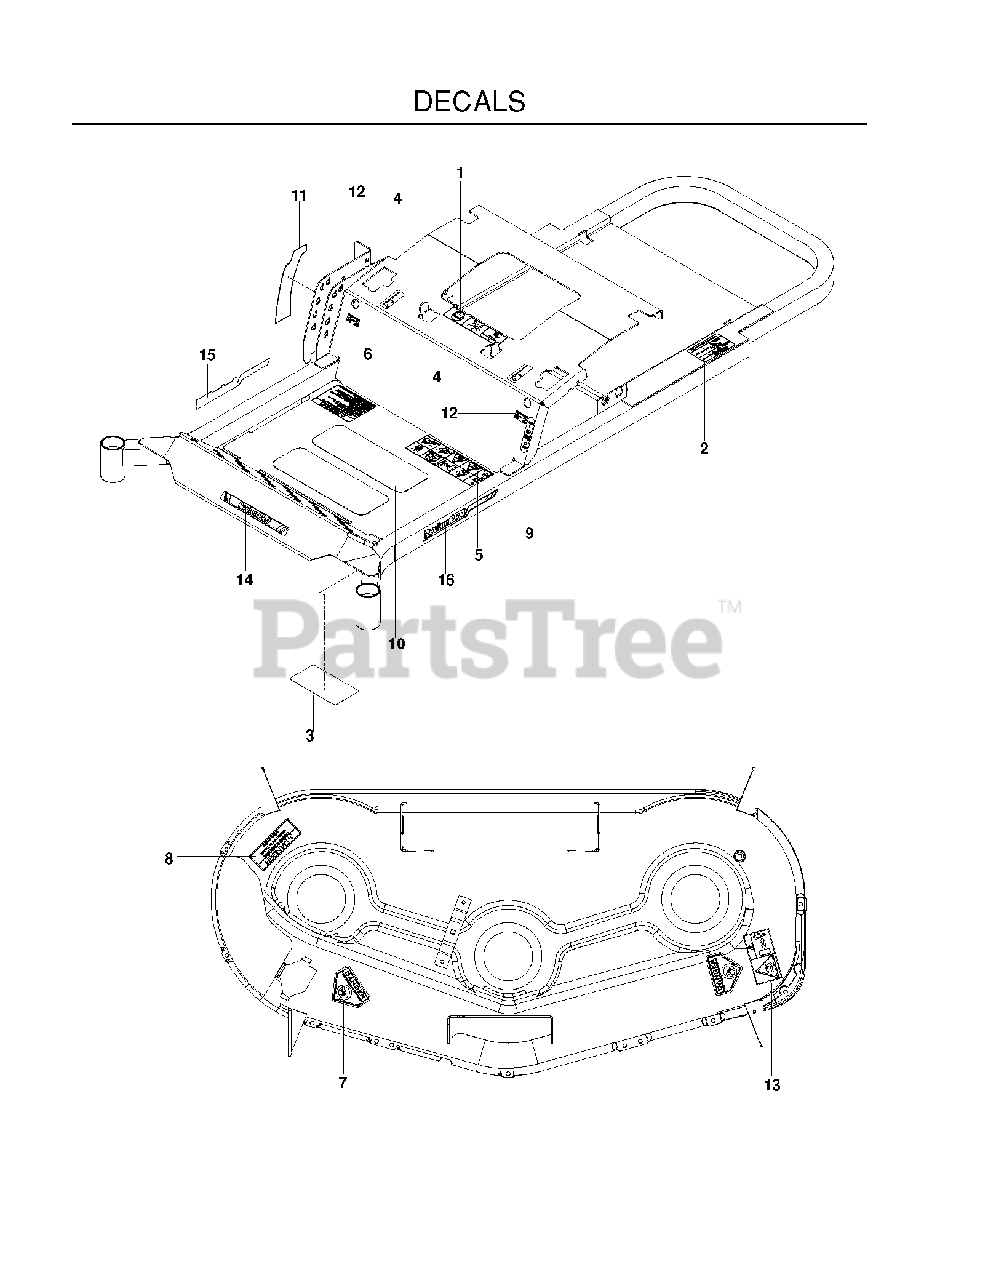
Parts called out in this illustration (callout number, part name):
1	DECAL, BATTERY
2	DECAL, DO NOT MOUNT
3	DECAL, SERVICE
4	DECAL, MOTION CONTROL, BLK
5	DECAL, WARNING
6	DECAL, WARNING
7	DECAL, CPSC
8	DECAL, DANGER
9	DECAL, PARK BRAKE
10	ANTI-SKID PAD
11	DECAL, HEIGHT
12	DECAL, F.S.T. BLK
13	DECAL, EURO SEVERING
14	DECAL, POULAN, FRONT
15	DECAL, POULAN, RIGHT
16	DECAL, POULAN, LEFT
